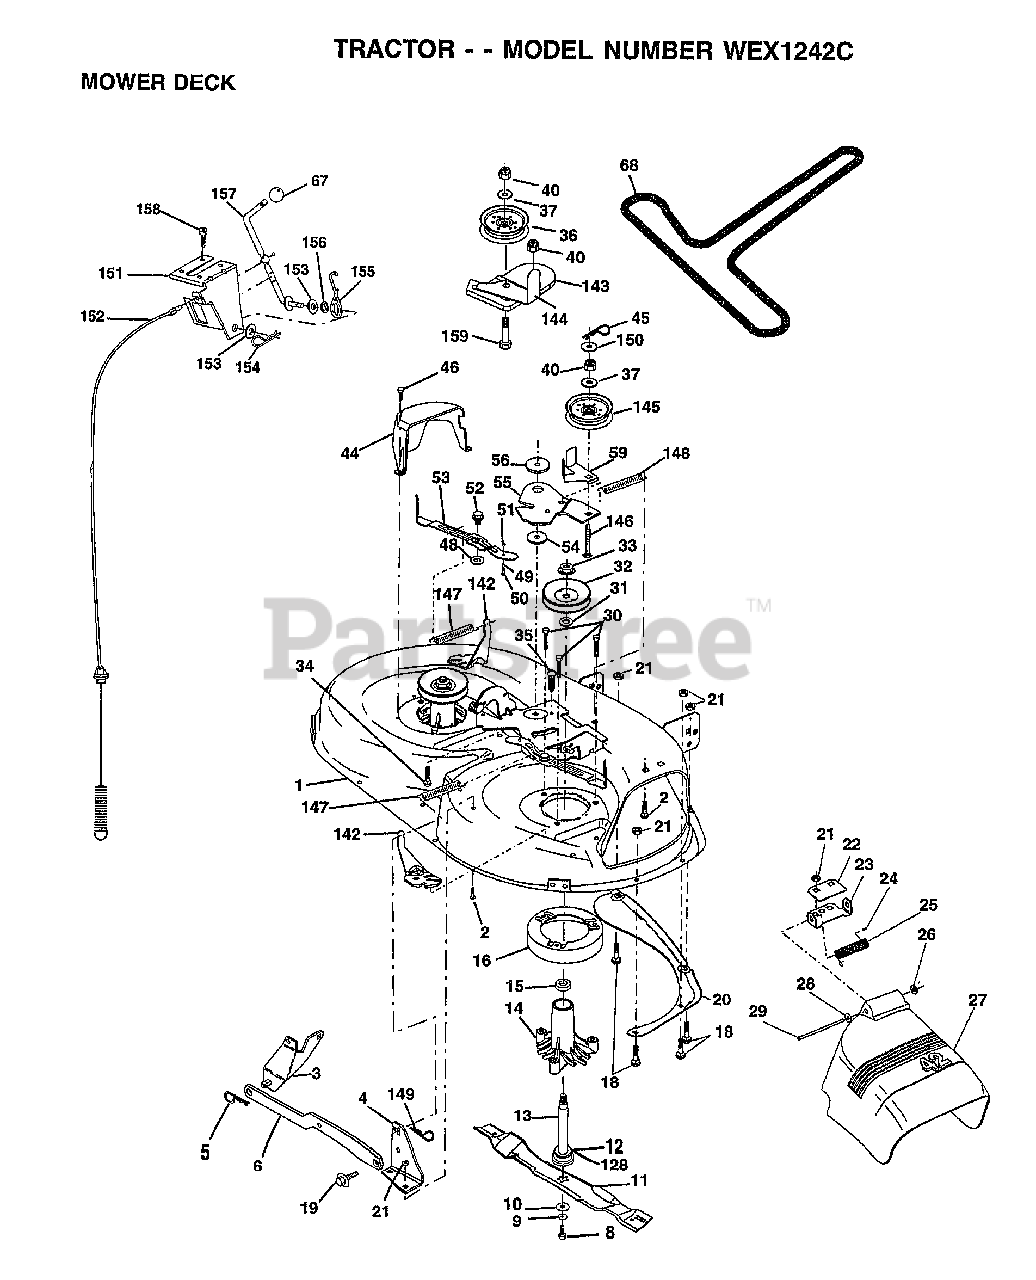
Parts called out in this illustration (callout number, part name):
1	MOWER DECK ASSY
2	BOLT
3	BRKT ASM SWAY BAR
4	BRACKET DECK
8	BLADE BOLT
10	WASHER.HARD.BLADE
11	"BLADE.42"" HIPERF"
12	BEARING.BALL
14	HSG ASM MANDREL
15	BEARING
16	STRIPPER RND MWR
18	BOLT
19	BOLT SHD 5/16-18
20	BAFFLE VORTEX 42
22	STIFFENER BRKT
23	DEFLECTOR BRKT
24	CAP-SLEEVE LT
25	SPRING TORSION
26	NUT PUSH M
27	SHIELD DEFLECTOR 42''
28	WASHER
29	HINGE ROD
30	"SCREW-THD ROLL,WA"
31	WASHER
32	PULLEY.MANDREL.42
34	BOLT
35	XMAS TREE FASTNER
36	FLAT IDLER PULLEY
37	WASHER
44	GUARD MAND LH BLK
45	RETAINER M
46	SCREW.1/4-20X5/8
48	HARD SMALL WASHER
49	ROLLER ASM-CAM
50	SHOULDER BOLT
51	LOCKNUT
52	LOCKNUT
53	BRAKE PAD ARM ASM
54	HARDENED WASHER
55	ARM-IDLER
56	SPACER.RETAINER.MOWER
59	GUARD IDLER TUV
67	KNOB T(3/8 HOLE)
68	BELT-V.SEC.46.KEL
121	BRACKET.EXTRD.GWL
128	WASHER.FELT.
142	ARM SPRING BRAKE MOWER
143	BRACKET ARM IDLER
144	KEEPER BELT CLUTCH CABLE
145	PULLEY IDLER FLAT
146	BOLT
147	SPRING EXTENSION
148	SPRING RETURN IDLER
149	RETAINER SPRING
150	WASHER PM
151	BRKT CLUTCH CABLE
152	"CABLE.CLUTCH.42"""
153	WASHER FLAT
154	SPRING RETAINER
155	SPRING RETENTION LVR CLUTCH CAB
156	SPACER
157	ROD.CLUTCH.CABLE.3/8
158	SCREW LT
159	BOLT
